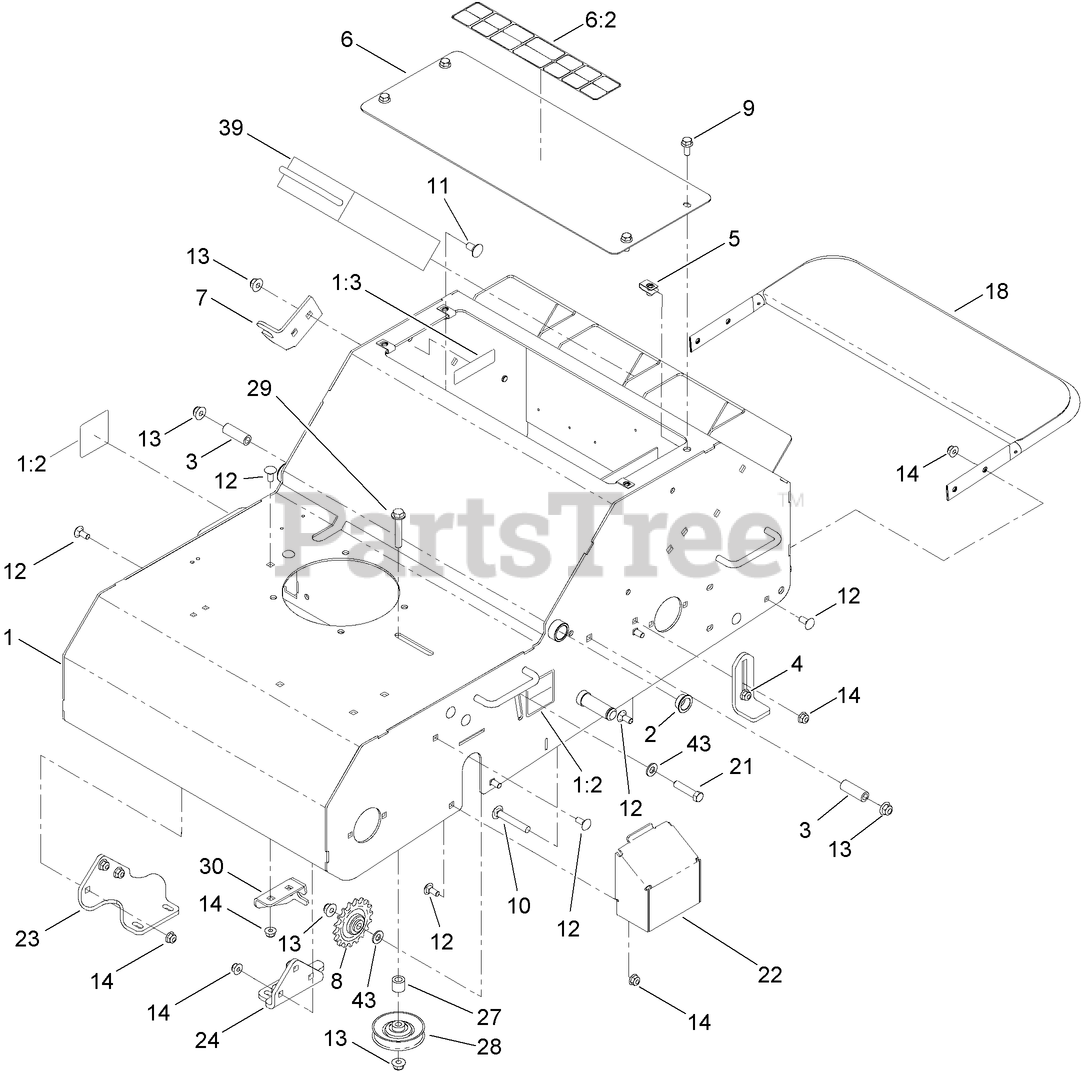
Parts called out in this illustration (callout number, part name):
1	FRAME ASM
1:2	DECAL-WARNING
1:3	DECAL-DANGER
2	BUSHING-BRONZE
3	SPACER
4	STOP-DEPTH
5	NUT-CLIP, U
6	COVER ASM
6:2	DECAL-WARNING, AERATOR
7	BRACKET-MOUNT, CABLE
8	SPROCKET-IDLER
9	SCREW-HHF
10	SCREW-CARR
11	SCREW-CARR
12	BOLT-CARR
13	NUT-HF, NI
14	NUT-HF, NI
21	SCREW-HH
22	COVER-TRANSAXLE
23	BRACKET-MOUNT AXLE, RH
24	BRACKET-MOUNT AXLE, LH
27	BUSHING-IDLER
28	PULLEY
29	SCREW-HH
30	BRACKET-MOUNTING, CABLE
39	WEIGHT-AERATOR
43	WASHER-FLAT
